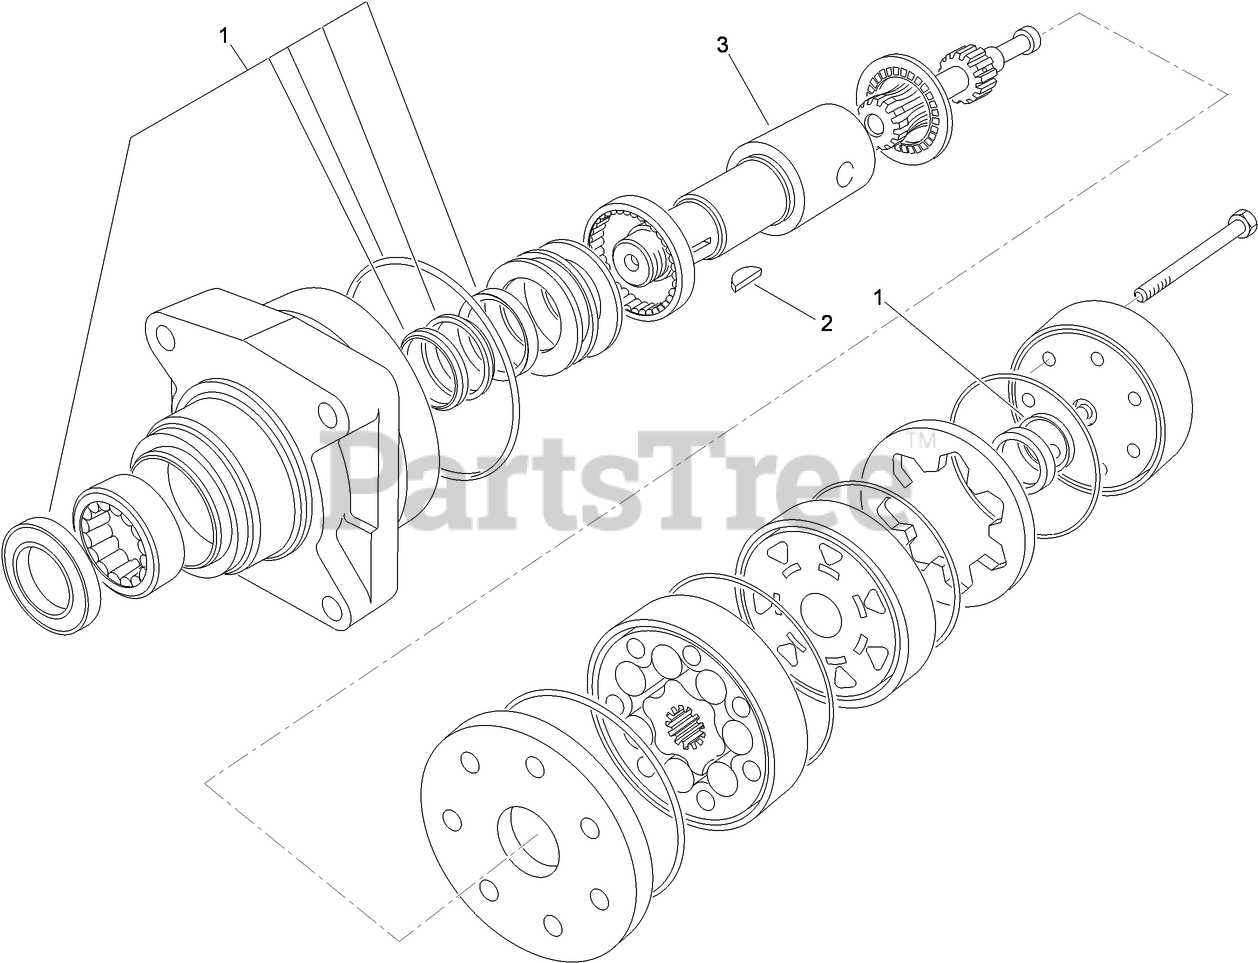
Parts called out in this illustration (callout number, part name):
1	SEAL KIT
2	KEY-WOODRUFF
3	SHAFT-COUPLING
